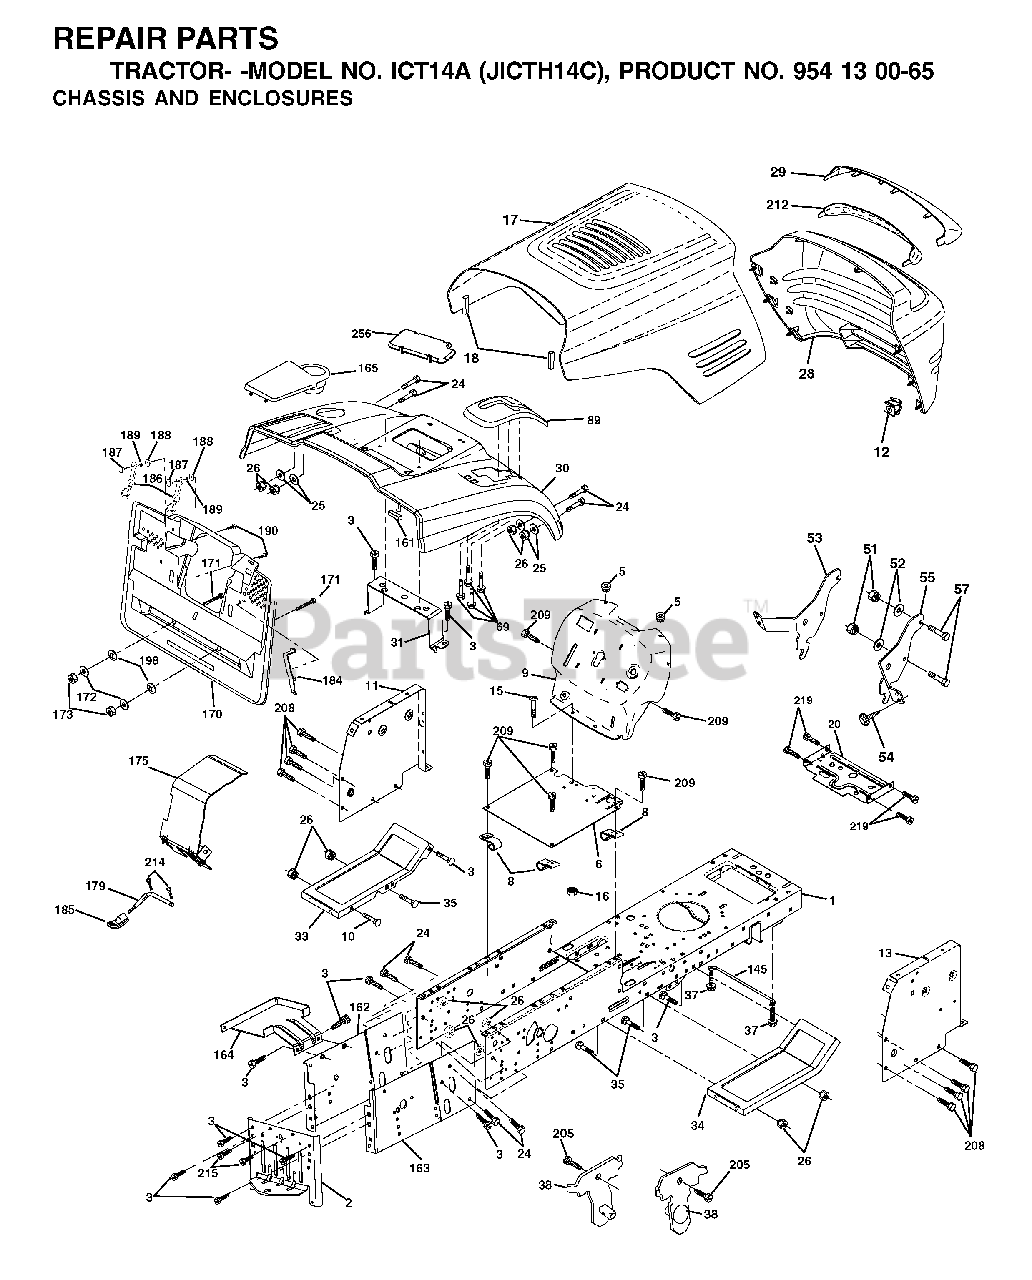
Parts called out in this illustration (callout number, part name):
1	CHASSIS
3	SCREW 3/8-16X3/4
5	BUMPER.RUBBER.HOOD
6	SADDLE FLAT
8	CLIP,INSULATOR
10	BOLT D
11	PANEL.DASH.LH.LTX
13	PANEL ASM, DASH RH
16	NUT
18	BUMPER HOOD T
20	PLATE MTG.BATTERY/FUEL TANK
24	BOLT
25	WASHER
26	NUT
31	BRACKET SUPPORT FENDER
35	BOLT
37	SCREW LT
51	LOCKNUT
52	WASHER
57	BOLT
69	SCREW.HI-LO.CONSOLE
145	ROD PIVOT CHASSIS/HOOD
161	EXTRUSION BUMPER
164	SUPPORT
171	BOLT
172	WASHER
186	LATCH ASSY
187	WELDNUT
189	LOCKWASHER
190	SCREW
205	SCREW LT
208	SCREW 3/8-16X1/2
209	SCREW, 3/8-16X3/4
214	RETAINER M
215	SCREW 5/16-18X1/2"
219	SCREW
